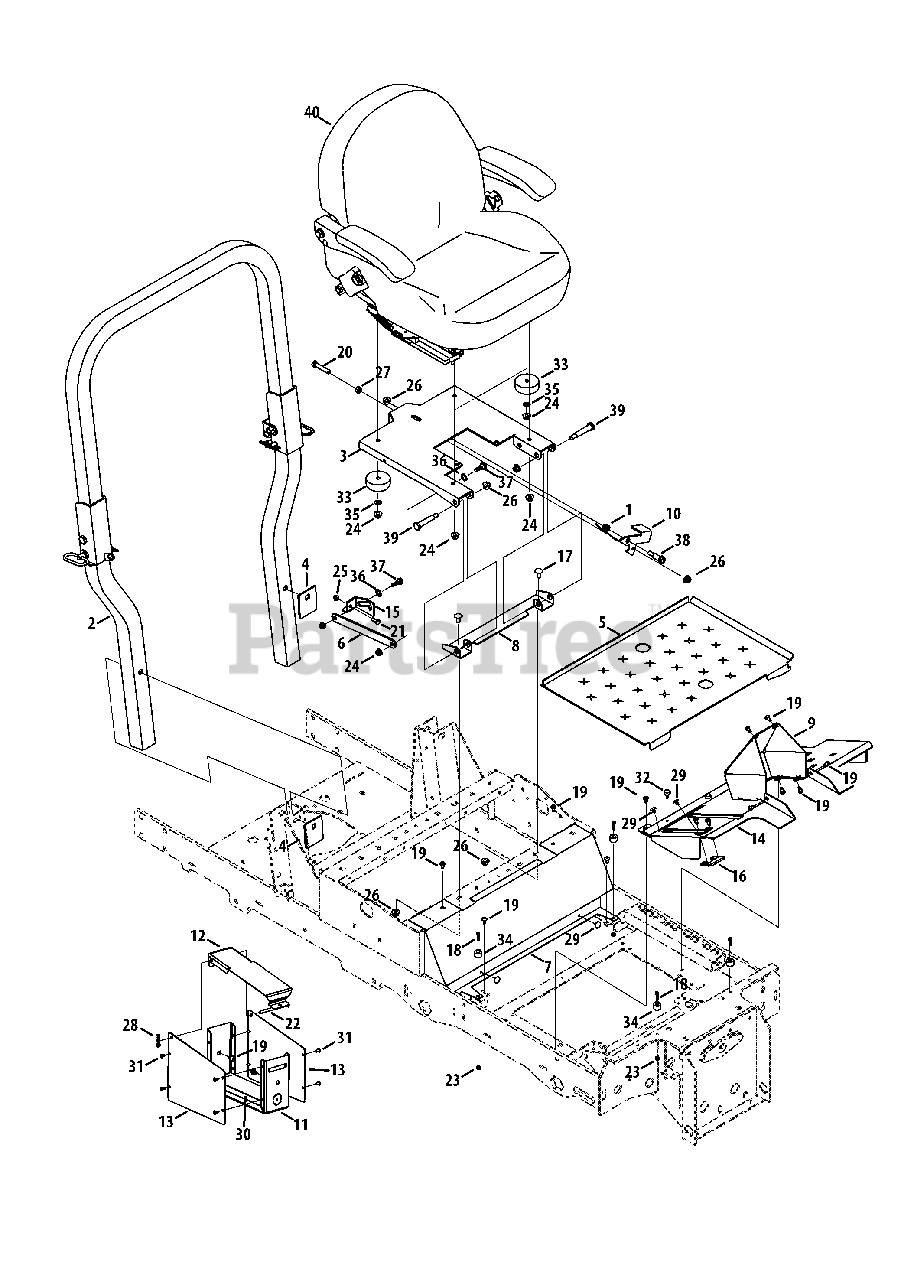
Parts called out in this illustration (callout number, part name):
1	Torsion Spring, .725 x 1.0 x .09
2	Folding ROPS Assembly
3	Seat Mounting Bracket
4	Deck Reinforcement Plate
6	Seat Lockout Bracket
7	Floor Panel Tray
8	Seat Mounting Bracket
10	Seat Lever Latch
12	Storage Box Lid
13	Storage Box Side Panel
15	Seat Lockout Mount
16	Stop Pedal Bracket
17	Carriage Bolt, 3/8-16 x .75
18	Socket Head Screw, 10-24 x .75
19	Screw, 1/4-20 x .5
20	Hex Cap Screw, 3/8-16 x 2.25
21	Hex Cap Screw, 1/4-20 x .75
22	Clevis Pin, .25 x 3.5
23	Nut, #10-24, Hexlock
24	Nut, 5/16-18, Flangelock
25	Nut, 1/4-20, Flangelock
26	Nut, 3/8-16, Flangelock
27	Nut, 3/8-16, Hex
28	Cotter Pin, Bow Tie
29	Clip, .250 Dia. x .500
30	Adhesive Pad
31	Rivet, 3/16 x .325
32	Bumper, .62 Dia. x .3
33	Rubber Bumper, 2.5 x 1.0
34	Rubber Bumper, .75 x .500
35	Washer, .344 x .688 x .065
36	Washer, .469 x .750 x .06
37	Shoulder Screw, .437 x .268, 5/16-18
38	Shoulder Bolt, .50 x .925, 3/8-16
39	Shoulder Bolt, .500 x 2.23, 3/8-16
40	Seat, w/ Suspension (60" only)
